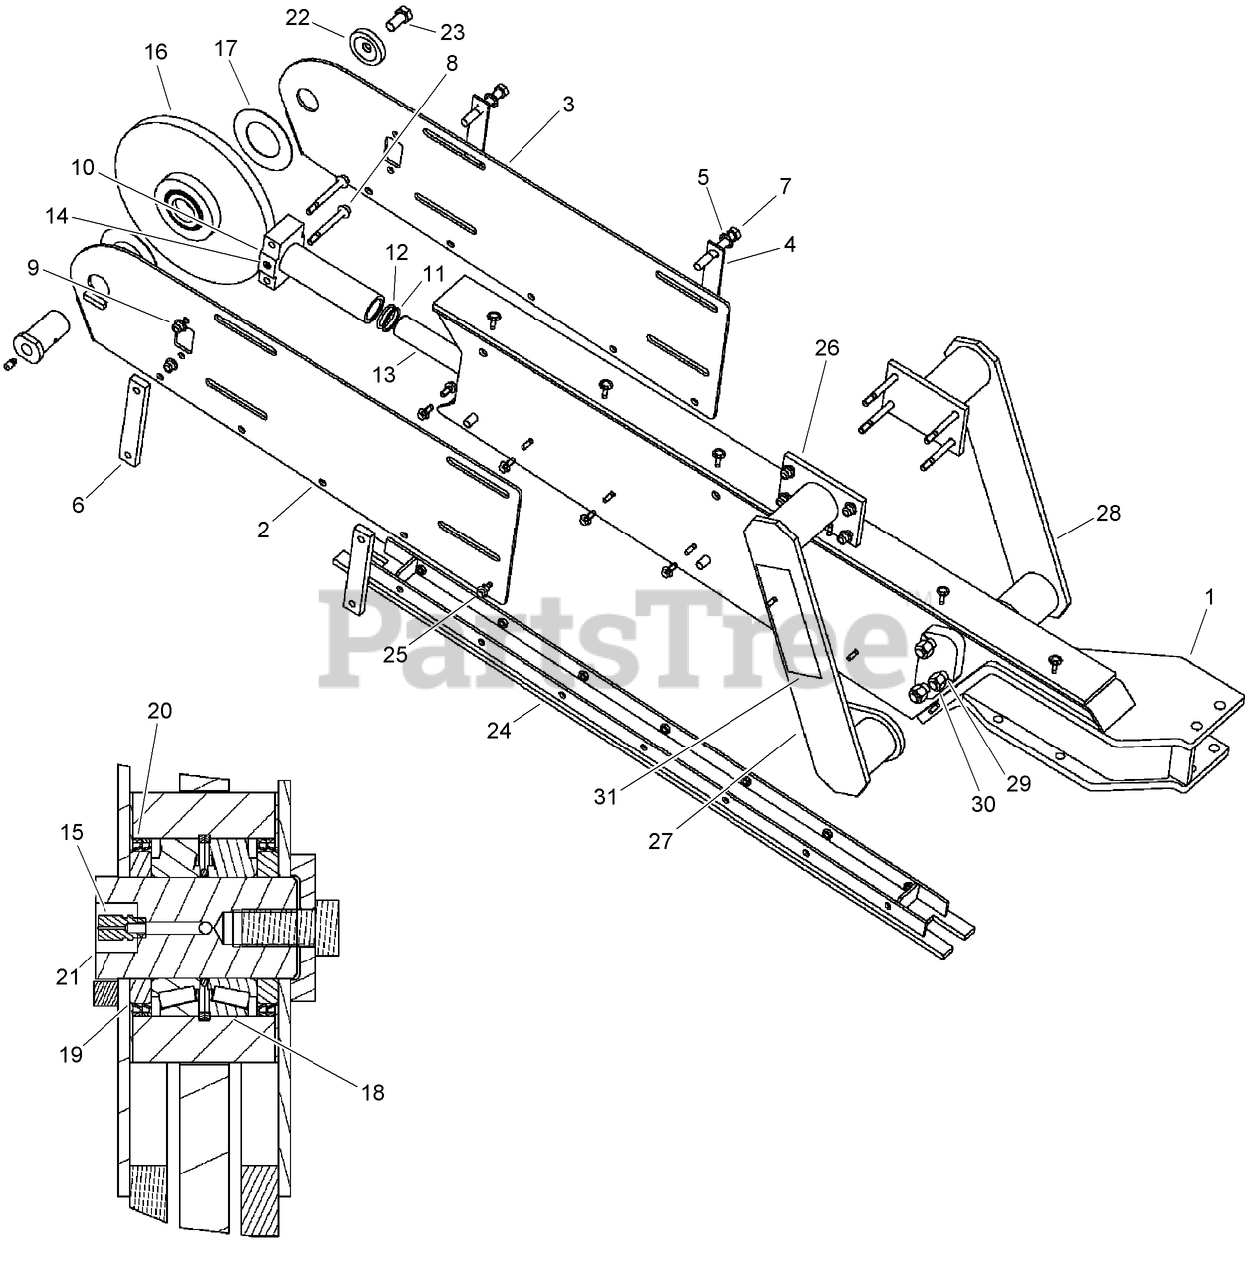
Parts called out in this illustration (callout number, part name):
1	BOOM-Rock, 5 foot
2	PLATE-Boom End (RH)
3	PLATE-Boom End (LH)
4	BAR-Clamp
5	WASHER-LOCK
6	BAR-Tapped
8	BOLT-HHF
9	NUT-HHF, LOCK
10	CYLINDER-Boom End
11	WASHER-BACKUP
13	ROD-BOOM, END (CYLINDER)
14	PLUG-BLEED
15	FITTING-LUBE, STRAIGHT
16	BOLLER-Boom End
17	WASHER-BOOM, END (ROLLER)
18	BEARING KIT
19	SPACER-bearing
20	SEAL-ROLLER
21	PIN-BOOM
24	CHANNEL-Wear Pad, 5\ Boom
25	SCREW-FLANGE
26	BAR-Wear Pad, Upper, 5\ Boom
27	MOUNT-Crumber RH
28	MOUNT-Crumber LH
30	NUT-Prev Trq 3/4 GRC CAD Direct
31	DECAL-Danger, Trencher Entanglement Hazard
